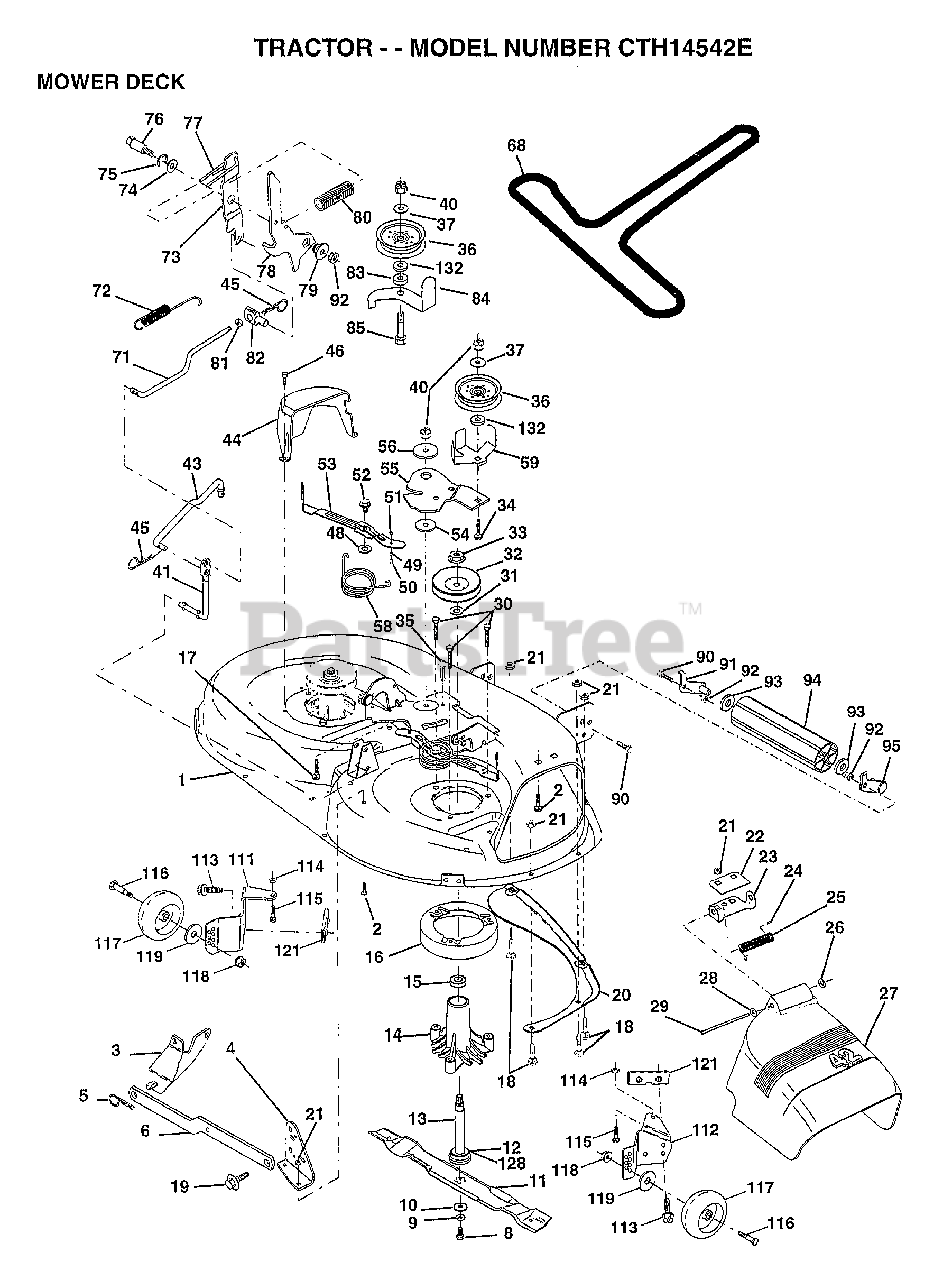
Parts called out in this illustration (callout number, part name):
1	DECK.WELD.42.
2	BOLT
3	BRKT ASM SWAY BAR
4	BRKT DECK SW BAR
8	BLADE BOLT
10	WASHER.HARD.BLADE
11	"BLADE.42"" HIPERF"
12	BEARING.BALL
14	HSG ASM MANDREL
15	BEARING
16	STRIPPER RND MWR
17	BOLT RDHD 3/8-16
18	BOLT
19	BOLT SHD 5/16-18
22	STIFFENER BRKT
23	DEFLECTOR BRKT
24	CAP-SLEEVE LT
25	SPRING TORSION
26	NUT PUSH M
27	DEFLECTOR.SHIELD
28	WASHER
29	HINGE ROD
30	"SCREW-THD ROLL,WA"
31	WASHER
32	PULLEY.MANDREL.42
34	BOLT
35	XMAS TREE FASTNER
36	FLAT IDLER PULLEY
37	WASHER
41	PIVOT ROD
43	ROD CLUTCH W/NIBS
44	GUARD MAND LH BLK
45	RETAINER M
46	SCREW.1/4-20X5/8
48	HARD SMALL WASHER
49	ROLLER ASM-CAM
50	SHOULDER BOLT
51	LOCKNUT
52	BOLT.SHLD.5/16-18
54	HARDENED WASHER
55	ARM-IDLER
56	SPACER RETAINER
58	SPRING TORSN BRAK
59	GUARD IDLER TUV
68	BELT.V.T-PATH
71	ROD CLUTCH 38/42
72	SPRING.EXT.RETURN
73	CLUTCH ARM SECOND
74	WASHER
75	RING
76	SHOULDER BOLT
77	SPRING KEEPER
78	LEVER ASM CLUTCH
79	BUSHING
80	SPRING.CLUTCH.MWR
81	NUT
82	TRUNION ADJ
83	WASHER
84	"KEEPER-BELT,FIXED"
85	BOLT RDHD 3/8-16
90	BOLT
92	NUT
93	WASHER
111	BRACKET.GWHL.LH.
112	BRACKET.GWHL.RH.
113	SCREW
116	BOLT.SHOULDER
117	WHEEL.GUAGE.MED.
118	LOCKNUT
119	WASHER
121	BRACKET.EXTRD.GWL
128	WASHER.FELT.
132	WASHER GT
